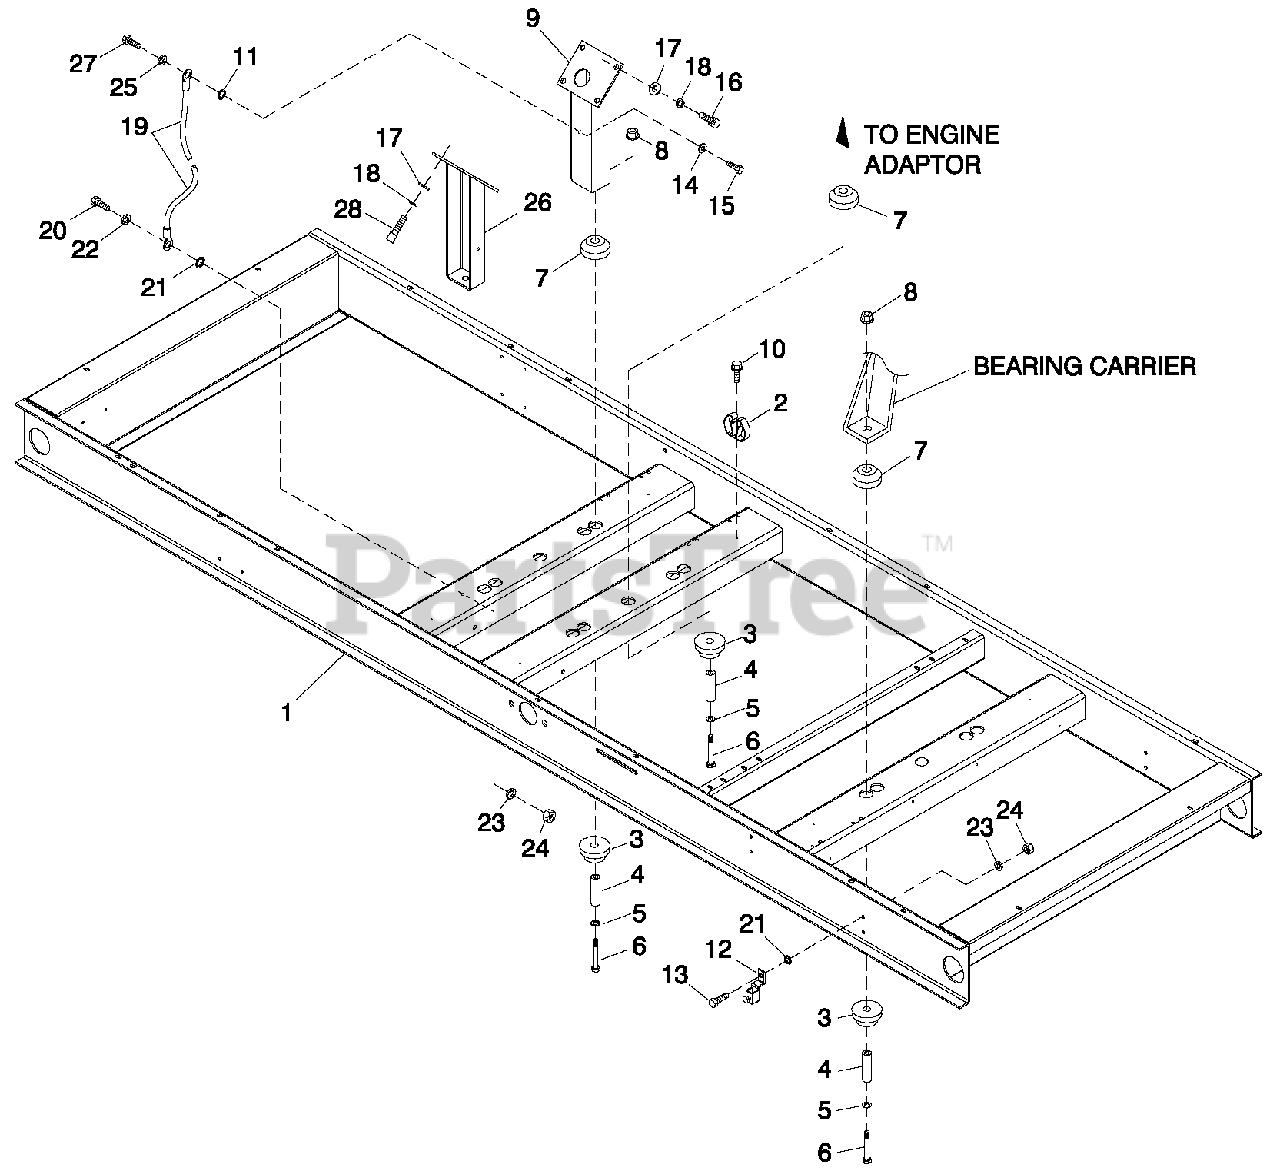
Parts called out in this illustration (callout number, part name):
1	BASE CPL 150KW2P
2	SPRING CLIP HOLDER ,37-.62
3	DAMPENER VIBRATION
4	SPACER .49 X .62 X 1.87 PWDR/ZINC
5	WASHER FLAT M12
6	SCREW HHC M12-1.75 X 85 G8.8
7	DAMPENER VIBRATION 50 WHITE
8	NUT LOCKING M12-1.75
9	SUPPORT ENG 5.4L LH/RH 6.8L RH
10	SCREW HHTT M4-0.7X8BP
11	WASHER SHAKEPROOFINT1/4
12	LUG SOLDERLESS 3/0-#4 X 13/32 CU
13	SCREW HHC M8-1.25X 25 G8.8
14	WASHER FLAT 1/4-M6 ZINC
15	NUT HEX M6 X 1.0 G8 YEL CHR
16	SCREW SHC M10-1.5 X 30 G12.9
17	WASHER FLAT 3/8-M10 ZINC
18	WASHER LOCK M10
19	ASSY WIRE 14.00"
20	SCREW HHC M8-1.25X 30 G8.8
21	WASHER SHAKEPROOF INT 3/8
22	WASHER LOCK M8-5/16
23	WASHER FLAT 5/16-M8 ZINC
24	NUT HEXM8-1.25G8YEL CHR
25	WASHER LOCK M6-1/4
26	SUPPORT, ENGINE 6.8L LH SIDE
27	SCREW HHC M6-1.0X 30 G8.8
28	SCREW SHC M10-1.5 X 60 G12.9
